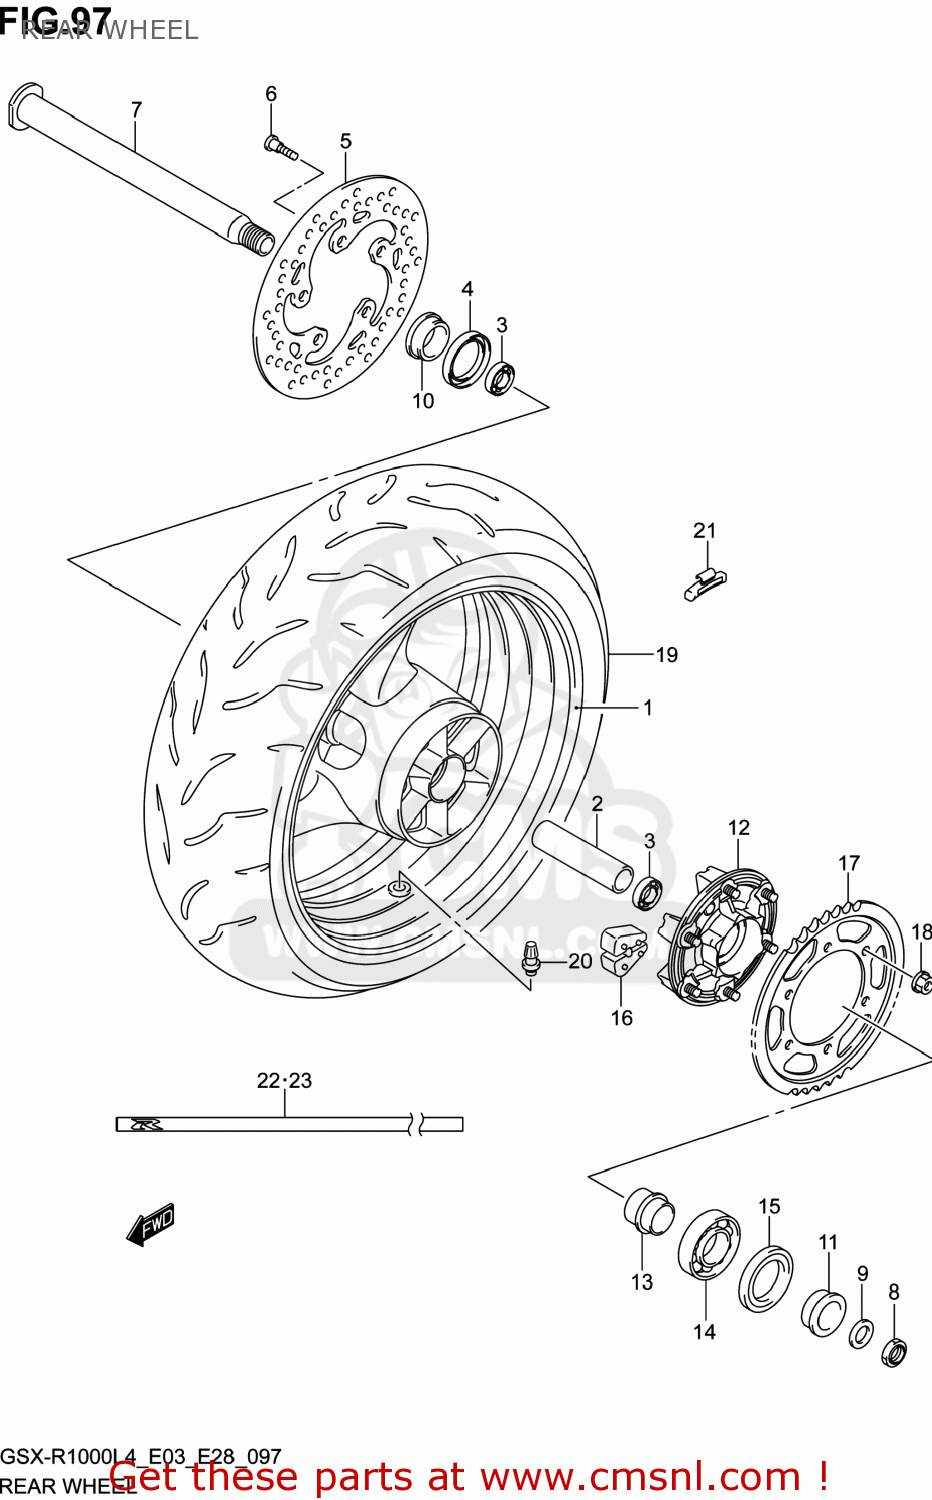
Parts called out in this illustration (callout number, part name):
1	WHEEL,RR(17M/CXMT6.00)
2	SPACER,RR HUB BEARING
3	BEARING(28X52X12)
4	SEAL,OIL(37X52X8)
5	DISC,RR BRAKE
6	BOLT(8X21)
7	AXLE,RR
8	NUT
9	WASHER(25.2X42X3.2)
10	SPACER,RR AXLE,R
11	SPACER,RR AXLE,L
12	DRUM,RR SPROCKET
13	RETAINER,RR SPROCKET DRUM
14	BEARING(32X65X17)
15	SEAL,OIL(39X65X7)
16	ABSORBER,RR HUB SHOCK
17	SPROCKET,RR(42T-530)
18	NUT
19	TIRE,RR
20	VALVE ASSY,WHEEL RIM(TR412)
21	BALANCER,WHEEL(10G)
22	TAPE,WHEEL FRONT,R
23	TAPE,WHEEL FRONT,L
